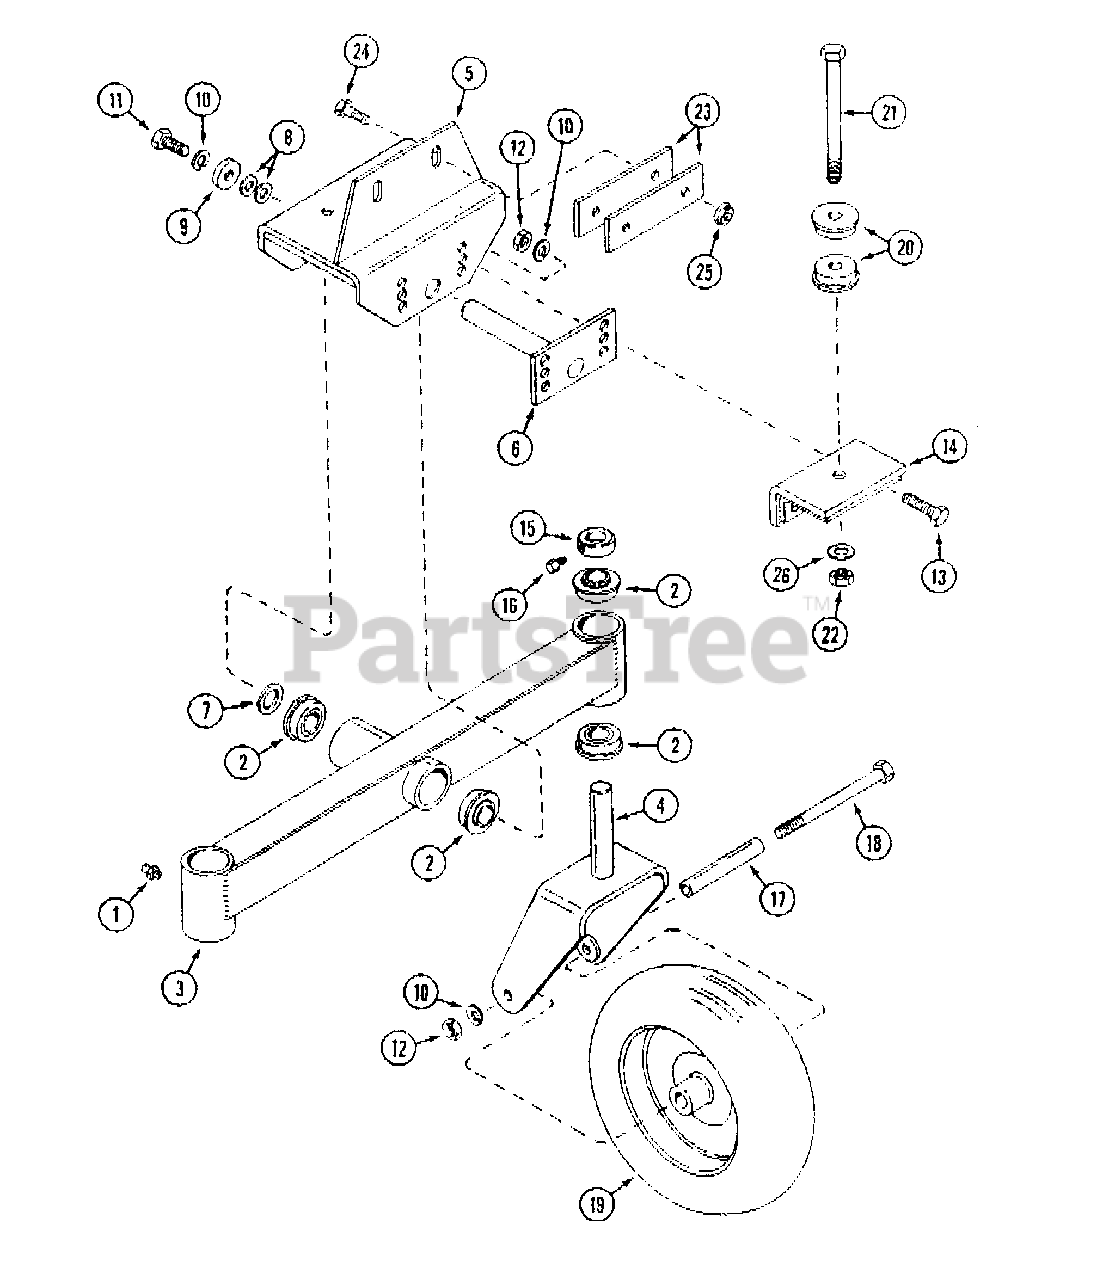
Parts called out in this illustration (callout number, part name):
1	FITTING - lubrication 1/4" - 28
2	BEARING - ball 1"
3	AXLE - dual wheel
5	MOUNT - axle
6	ROD - axle pivot
7	WASHER - 1" x 1-3/4"
8	WASHER - 1/2" x 1"
9	WASHER - 1/2" x 1-3/8"
10	LOCKWASHER - 1/2"
11	BOLT - 1/2" - 13 x 1-1/4"
12	NUT - 1/2' - 13
13	BOLT - 1/2" - 13 x 1-3/4"
14	MOUNT - axle, front extension
15	COLLAR - set 1"
16	SCREW - set 6/16" - 18 x 1/2" square head
18	BOLT - 1/2" - 13 x 7"
19	WHEEL ASSEMBLY
20	BUSHING - tail wheel hub
21	BOLT - 5/8" - 11 x 7-1/2"
21	BOLT - 5/8" - 11 x 11"
22	NUT - 5/8" - 11
23	PLATE - stiffener
24	BOLT - 3/8" - 16 x l-1/4"
25	NUT - 3/8" - 16 flange lock
26	WASHER - 5/8" x 1-1/2"
